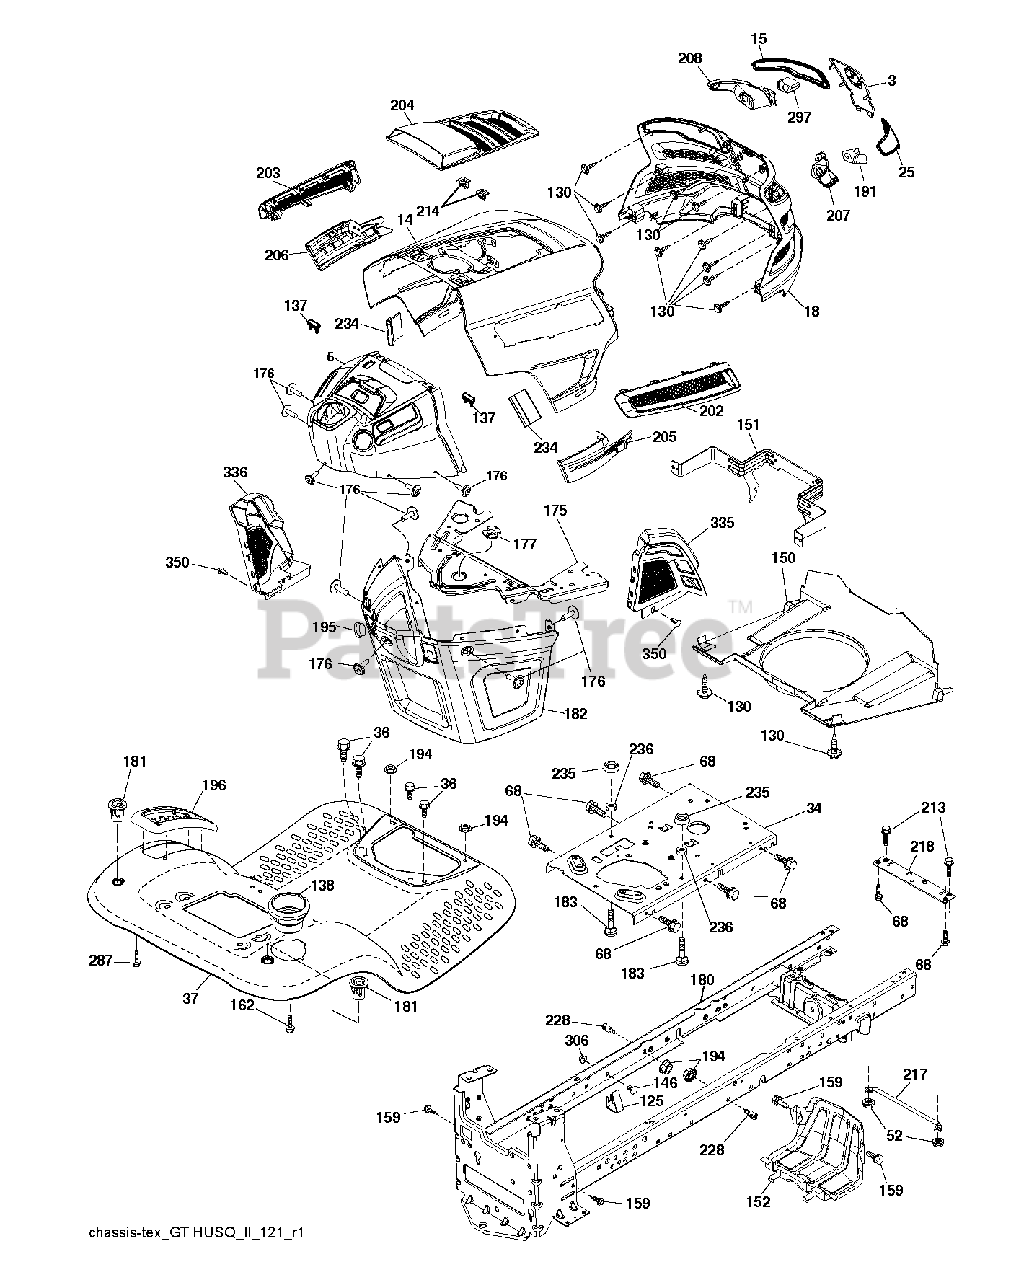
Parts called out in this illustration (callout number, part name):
3	APPLIQUE.SUBASM.GT.HUSQ.II
5	ASSY.DASH.W/BUMPERS.READYSTART
14	HOOD.ASM.HUSQVARNA.GT.TEX.ORAN
15	LENS.HEADLIGHT.LH.GTII.2011
18	GRILLE.SUBSTRATE.2011.
25	LENS.HEADLIGHT.RH.GTII.2011
34	PLATE.ENGINE.WELDED.CHASSIS
36	SCREW 5/16"
37	FENDER.TLT.PDL.CNTRL.W/CPH.ORG
52	LOCKNUT
68	SCREW LT
125	CLIP.FUEL.LINE
130	SCREW.#10 X 0.750.BOS
137	BUMPER DASH
138	HOLDER.CUP.LT.GREY
146	BOLT.RDHD.SHT.SQNK.3/8-16X5/8
150	AIR.DUCT.GTV.BLACK
151	BRACKET.PIVOT.HOOD.GT.HUSQ.II
152	SHIELD.BROWNING.PNT.GT.V2
159	SCREW, 3/8-16X3/4
162	SCREW.HI-LO.CONSOLE
175	PLATE.CROSSMEMBER.HUSQ
176	SCREW.#10-24X5/8.RN.QU
177	BUSHING, STEERING
180	CHASSIS
181	BUSHING.MNT.FEND.CRGO.TEX.49
182	DASH.LOWER.COMMON.12V.ADAPTOR
183	BOLT.5/16-18X1-1/4 FULL THD
191	INSERT.REFLECTIVE.RH.HUSQ.GTII
194	NUT LOCK HEX FLANGE 5/16-18
195	PLUG.HOLE.DASH.LOWER.12V.BLK
196	DECKLFT.CONSOL FULL ASSM GREY
202	VENT.SIDE.RH.GT.HUSQ.II.
203	VENT.SIDE.LH.GT.HUSQ.II.498
204	VENT.TOP.HUSQ.GT2
205	SIDE.TRIM.RH.GT.HUSQ.II
206	SIDE.TRIM.LH.GT.HUSQ.II.GRAY
207	BEZEL LIGHT.RH.GT.II.MYLAR
208	BEZEL LIGHT.LH.GT.II.MYLAR
213	BOLT
214	CLIP.RETAINER.TINNER.
217	ROD.PIVOT.HOOD
218	X-PIECE.HOOD.STOP.NON/
228	STUD.FASTNER.W/ANTI-ROTATE
234	BUMPER.HOOD.TEX.HUSQVARNA
235	SPACER FENDER
236	NUT.CENTERLOCK.5/16-
287	SCREW 1/4X20
297	INSERT.REFLECTIVE.LH.HUSQ.GTII
306	NUT LOCK FLG 3/8-16 UNC
335	COVER.LOWER.DASH.RH.BLACK
336	COVER-LH.LOWER.DASH.GT2.BLACK
350	CLIP.X-MAS.TREE
